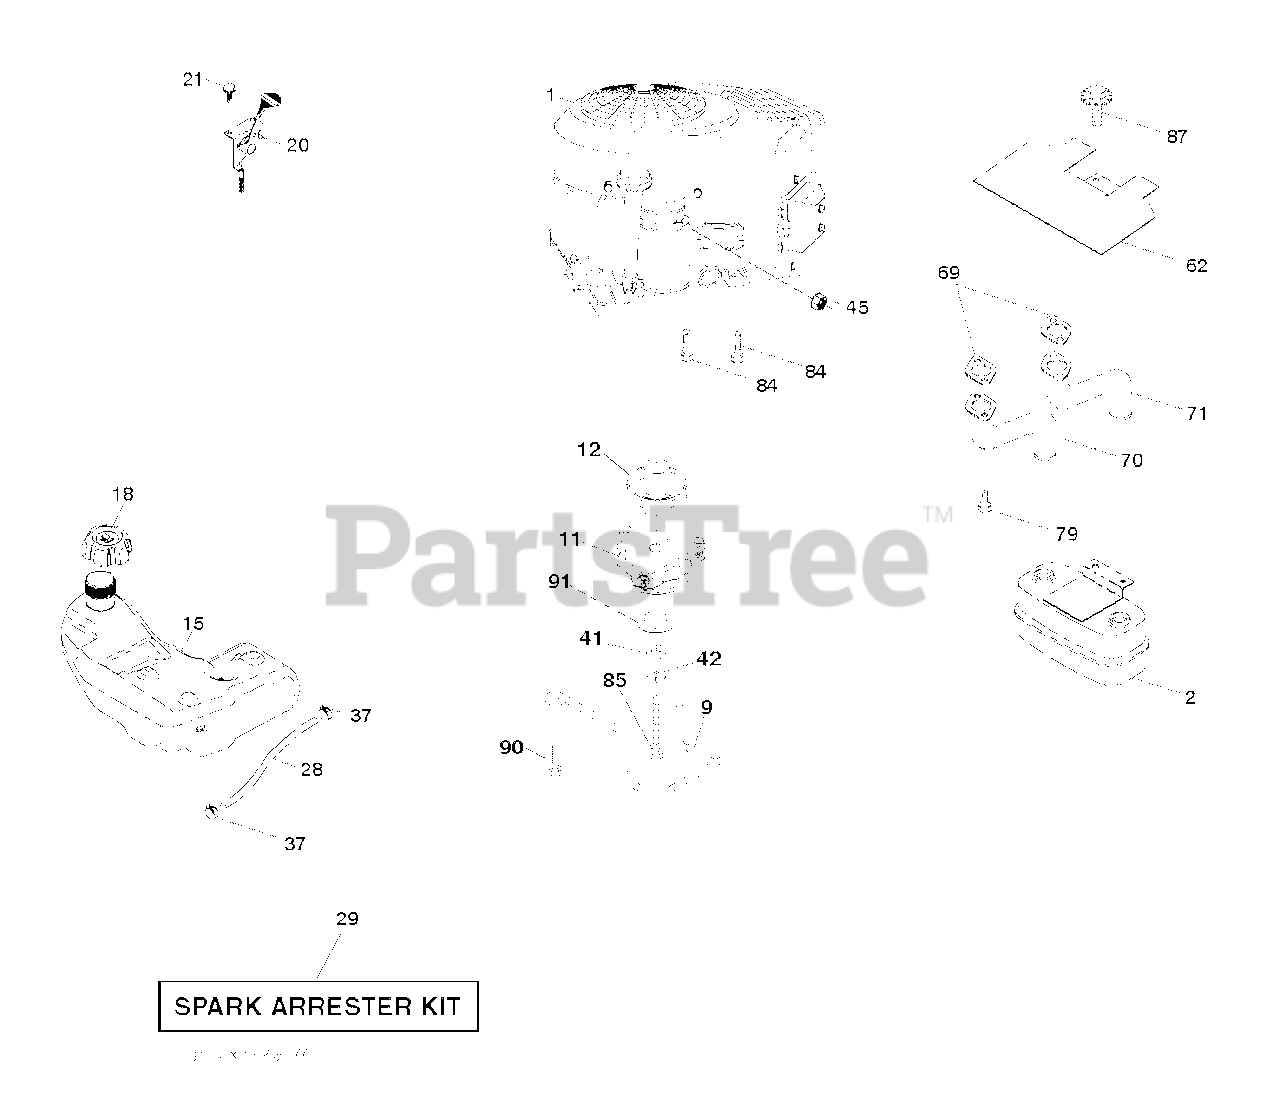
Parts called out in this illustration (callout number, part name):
2	MUFFLER.ASM.TWN.EXTNDED.DFLCTR
9	KEEPER.BELT.ENGINE.4.2
11	CLUTCH.ELECTRIC.LT.48"*
12	PULLEY.ENGINE.TUFFTORQ
15	TANK.ASSY.3.GAL.EPA
18	CAP.ASM.FL.RITCH.3"E10.SYM.498
20	CONTROL.TH/CK.COBRA.B&S.TWN.
21	SCREW.#10 X 0.750.BOS
28	LINE.FUEL.64"REAR.EMIS
29	KIT.SPARK ARRESTOR 794945 B&S
37	HOSE CLAMP
42	LOCKWASHER
45	NUT
62	SHIELD.HEAT.MUFFLER
69	GASKET.MUFFLER
70	RP.EXHAUST.TUBE.LH.BS/TWIN
71	EXHAUST.TUBE.RH.BS/TWIN
79	SCREW.SOCKET.HEAD.5/16-18
84	SCREW.3/8-16
85	BOLT HEX 7/16-20X4-1/4"
87	Bolt, 5/16-18 X 1-3/4
90	SCREW 3/8-16X1
91	BUSHING.1.375OD
